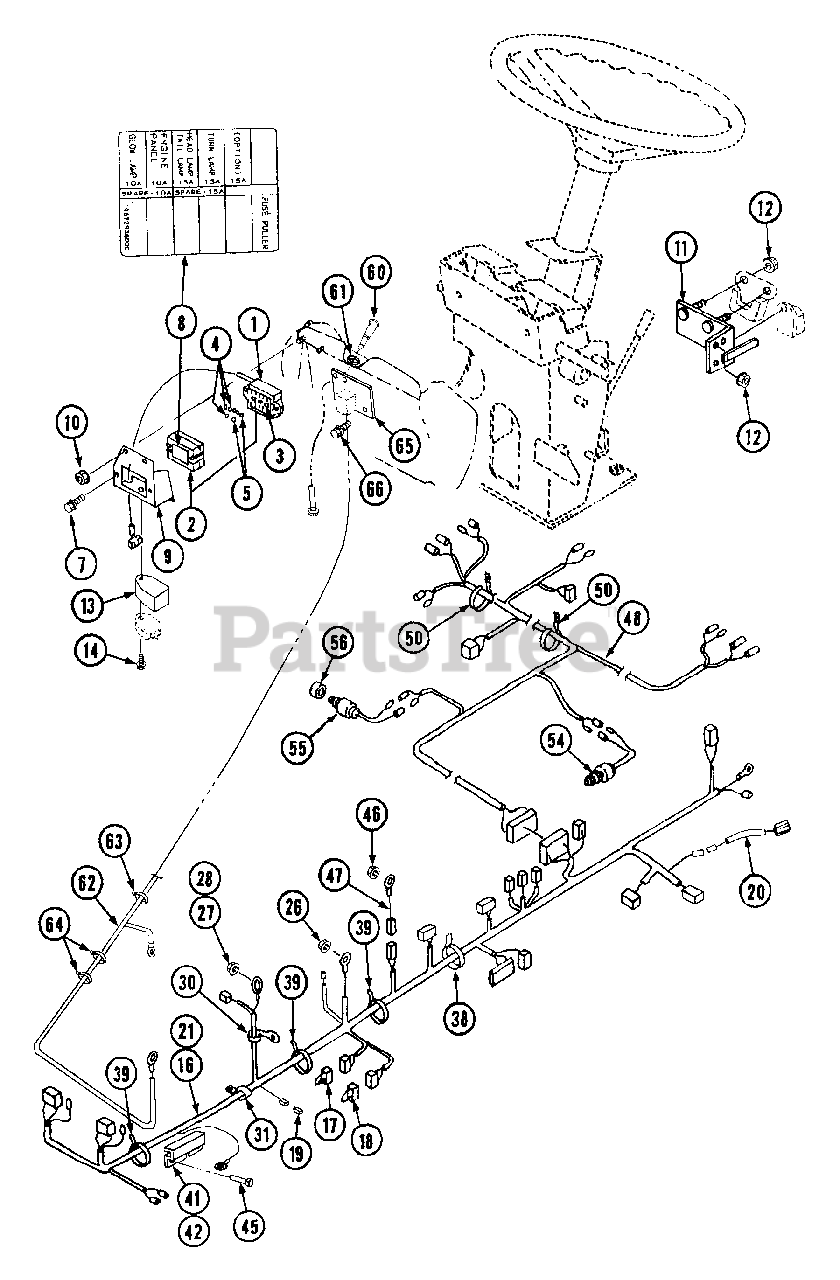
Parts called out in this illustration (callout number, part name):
13	Cover
14	Bolt
16	Harness
20	Wire Lead
21	Harness
27	Nut
31	Clamp
42	Cover
54	Switch, Safety
55	Switch
60	Cable, Flexible
62	Harness H
63	Band Wire
64	Band Wire
65	Bracket
66	Bolt
